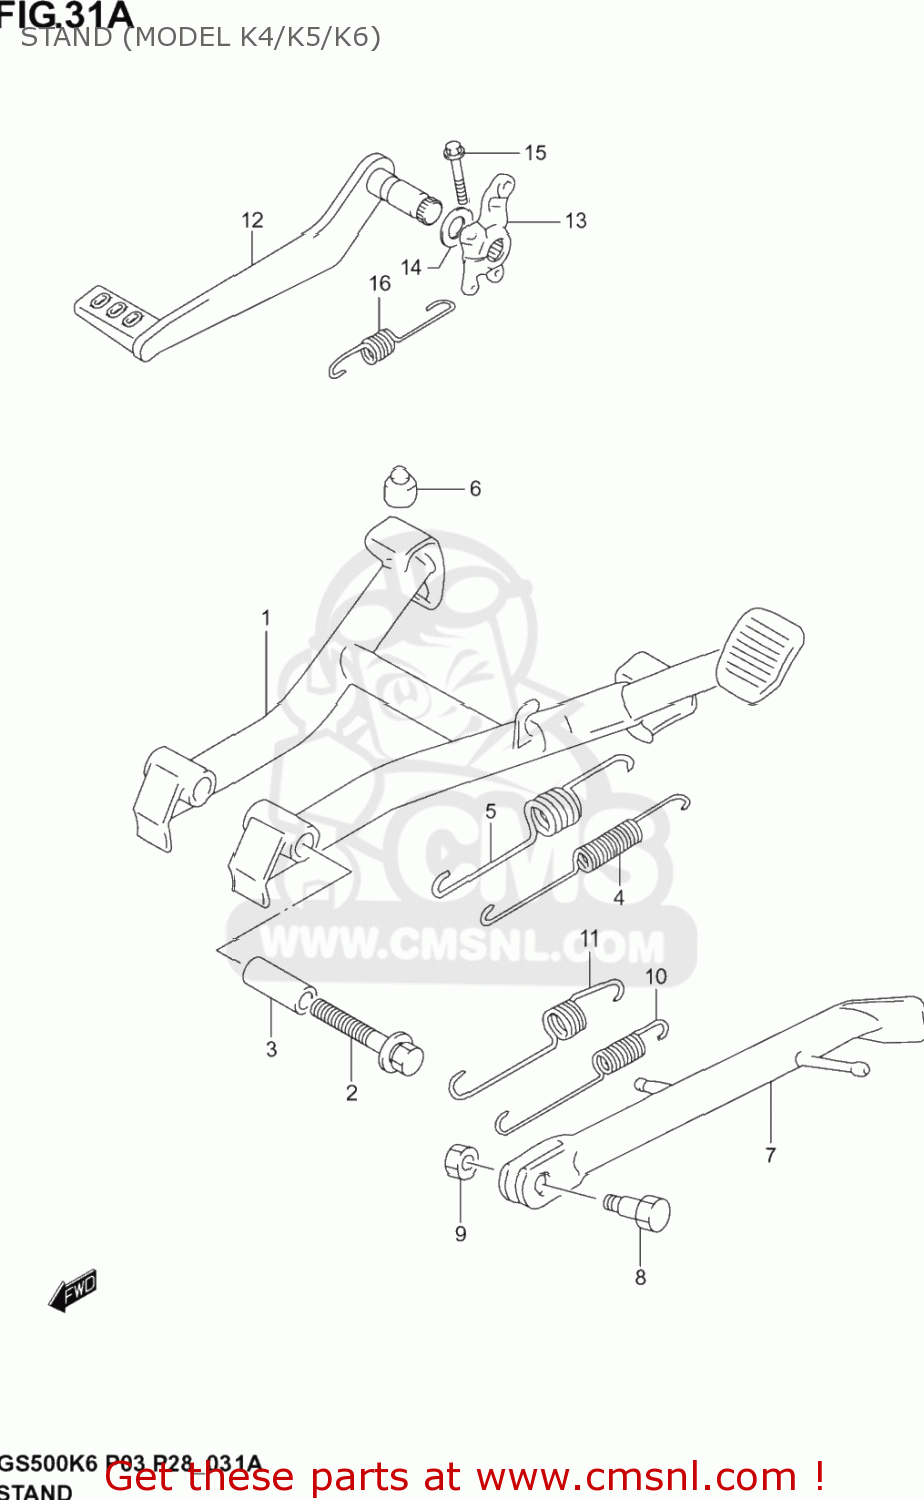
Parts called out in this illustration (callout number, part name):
1	STAND, CENTER
2	BOLT
3	SPACER(10X16X38.8)
4	SPRING
5	SPRING OUTER
6	CUSHION
7	STAND,PROP
8	BOLT(10X34)
9	NUT
10	SPRING
11	SPRING
12	PEDAL, BRAKE
13	ARM, BRAKE ROD
14	WASHER
15	BOLT
16	SPRING
